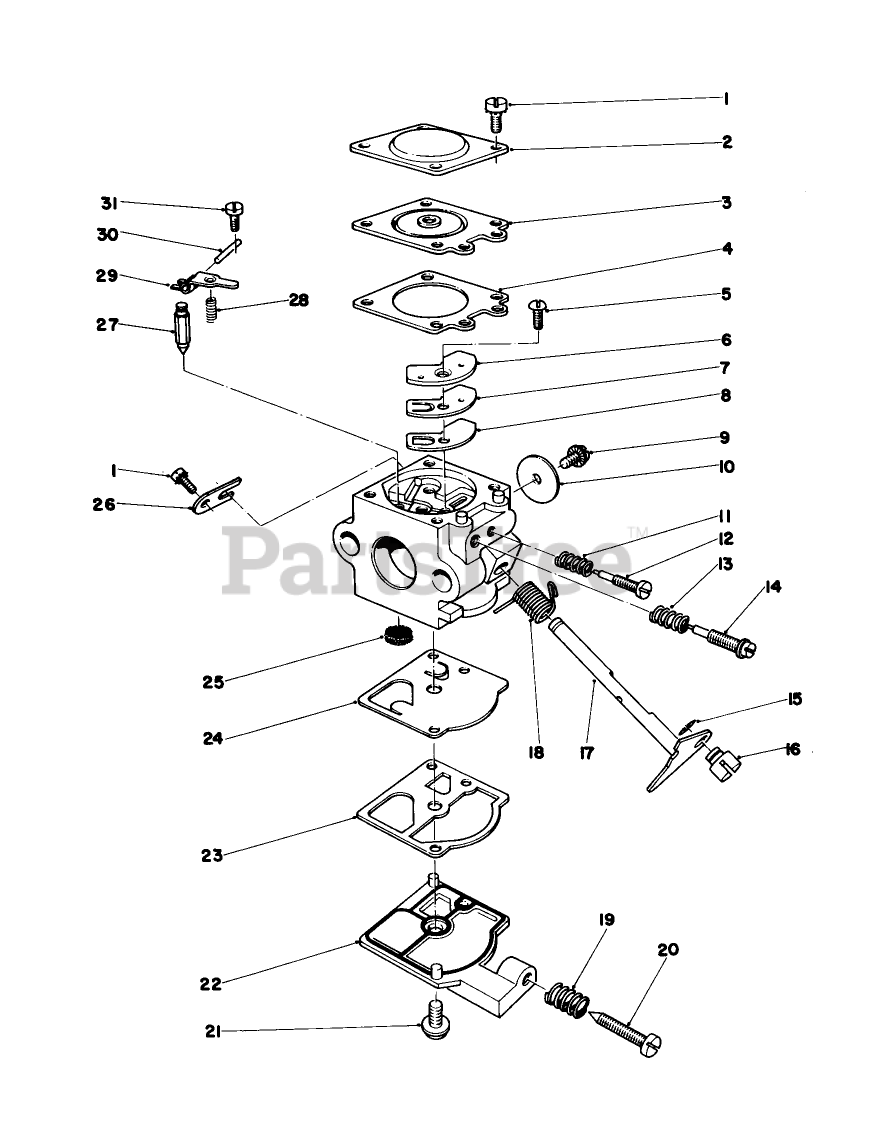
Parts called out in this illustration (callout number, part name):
1	Screw
2	Cover, Diaphragm
3	METERING DIAPHRAGM
4	Gasket, Diaphragm
5	Screw-Circuit Plate
6	Plate, Circuit
7	Diaphragm Circuit Plate
8	Gasket-Circuit Plate
9	Screw
10	Valve, Throttle
11	Spring, Needle
12	Idle Needle
13	Spring, HS Needle
14	Needle, HS
16	Swivel
17	THROTTLE SHAFT ASM
18	Spring-Throttle Lever
19	Spring, Idle Screw
20	Screw, Idle Adjust
21	Screw
22	Cover, Fuel Pump
23	PUMP GASKET
24	Diaphragm Fuel Pump
25	Screen Inlet
26	Clip Throttle Shaft
27	INLET NEEDLE VALVE
28	Spring, Lever
29	Lever Metering
30	Metering Lever Pin
31	Screw-Metering Pin
